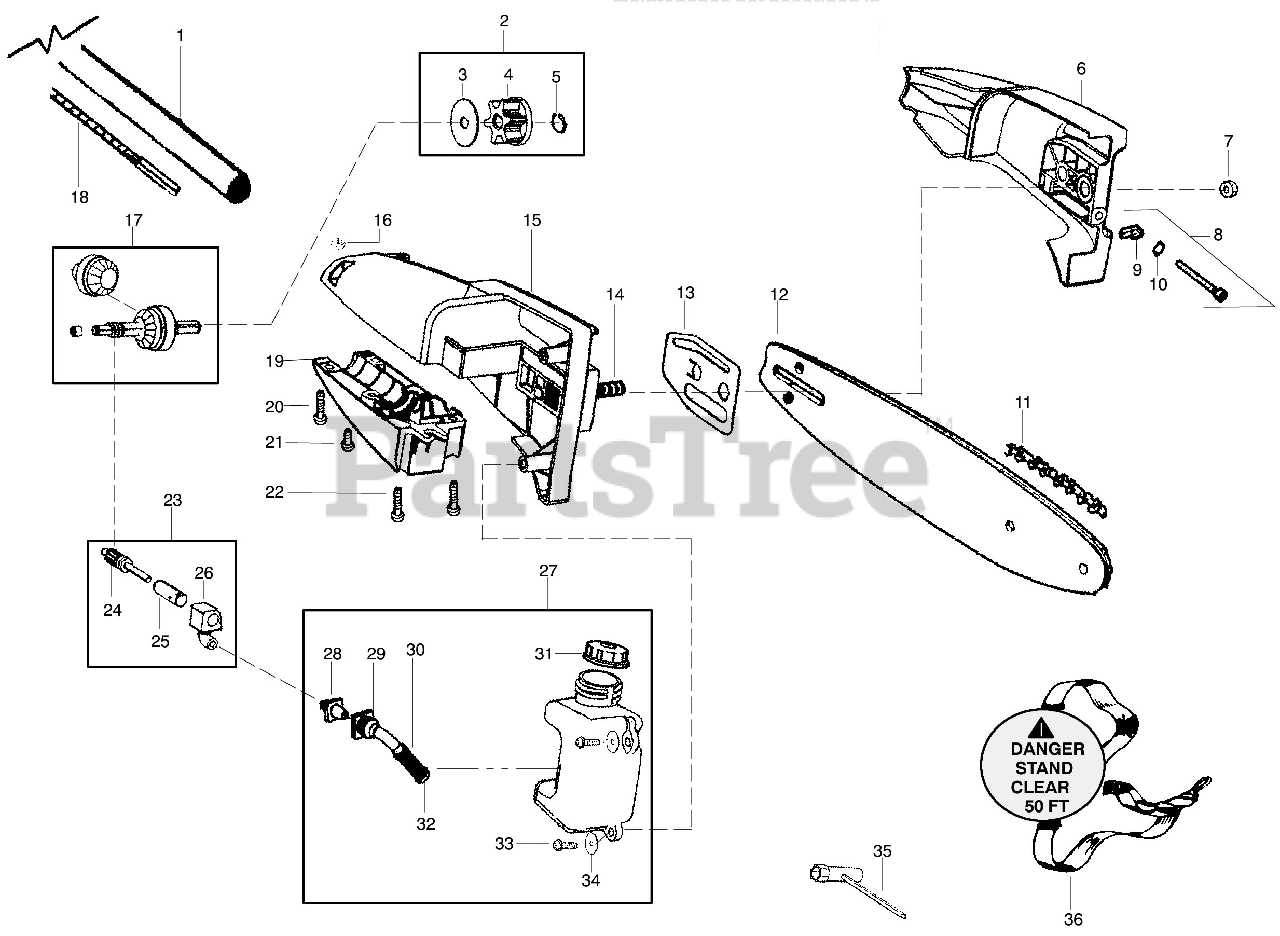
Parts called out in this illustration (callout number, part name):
1	Assy-Driveshaft
2	Kit-Sprocket Assy.
4	Sprocket
5	Retainer-Sprocket
6	Assy-Bar Clamp
7	Nut-Bar Mounting
8	Kit-Bar Adjust
9	Pin-Bar Adjust
10	Retainer-Bar Adjust
11	Chain-8"
13	Plate-Bar pad
14	Bolt-Bar
15	Hsg.-Upper
17	Kit-Gear Assy
18	Flex shaft - lower
19	Hsg.-Lower
21	Screw-Align
23	Kit-Oil Assy
24	Assy-Gear Plunger
26	Block-Oil
27	Assy-Oil Tank
28	Fitting-Oil Line
29	Intake-Oil Line
30	Filter-Oil
31	Cap-Oil
32	Plug-Oil Filter
35	Wrench-Bar
36	Strap-Shoulder
